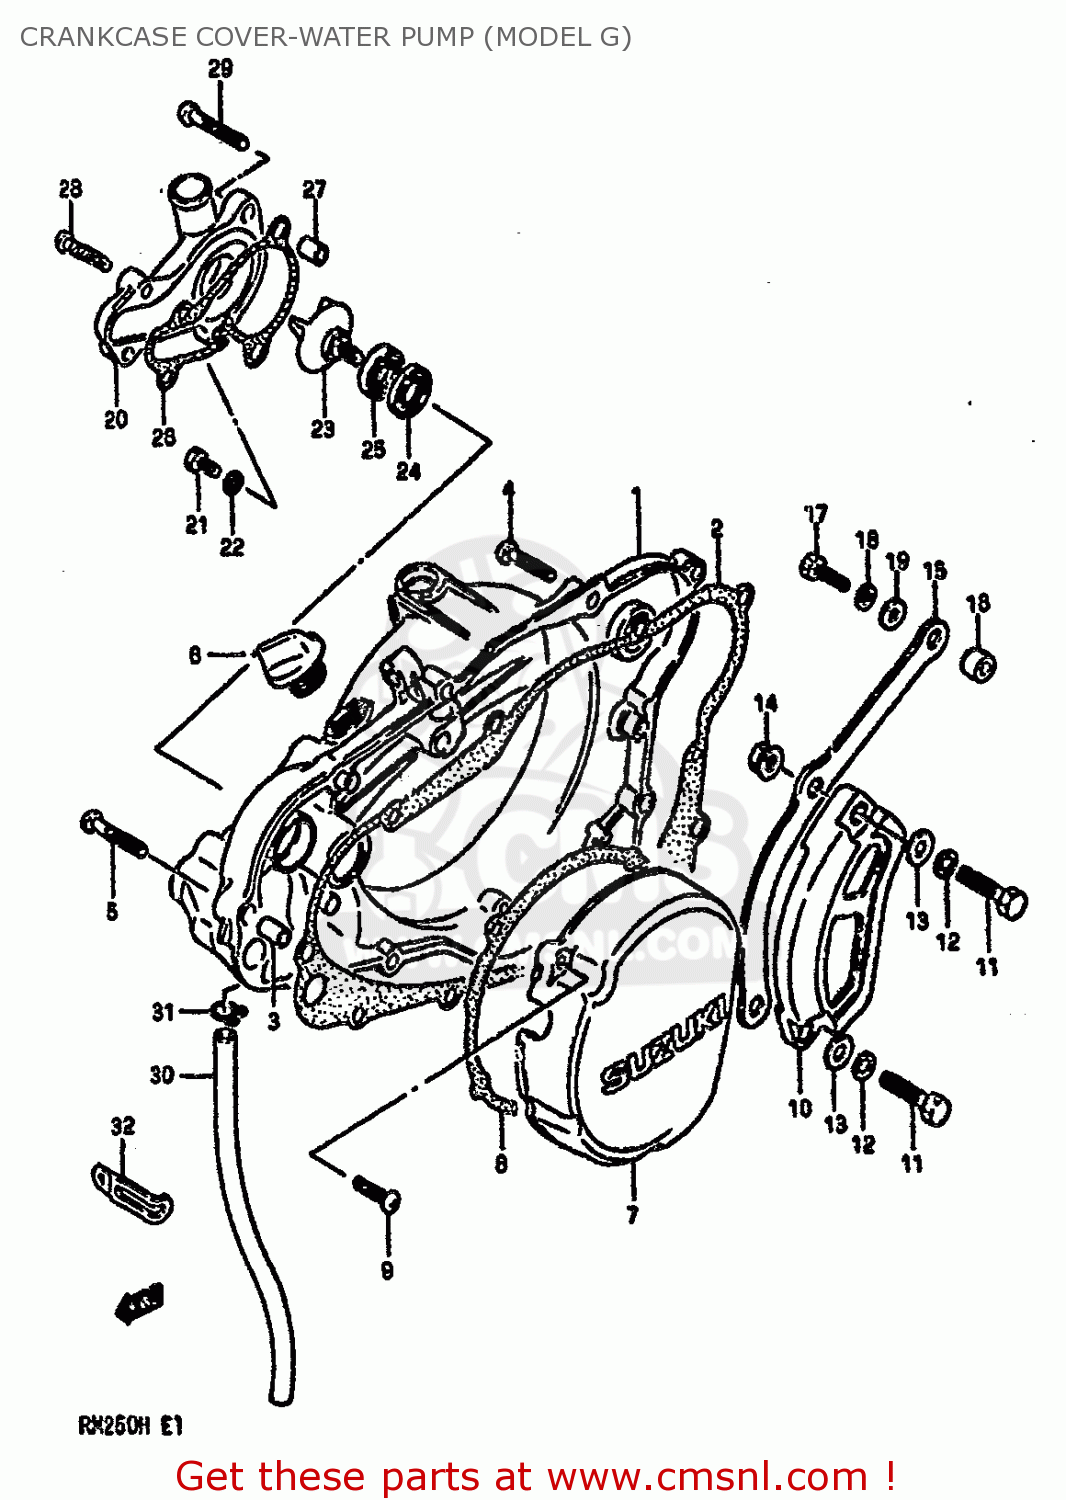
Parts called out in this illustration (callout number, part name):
1	COVER SET,CLUTCH
2	GASKET,CRANKCASE (MCA)
3	PIN
4	SCREW
5	SCREW (6X35)
6	PLUG SET
7	COVER,MAGNETO
8	GASKET,MAGNETO COVER (MCA)
9	SCREW
10	COVER,SPROCKET
11	BOLT (8X30)
12	LOCK WASHER
13	WASHER
14	NUT
15	PLATE,FRONT CHAIN GUIDE
16	SPACER (6.5X12X8)
17	BOLT
18	WASHER,LOCK
19	WASHER
20	CASE COMP,WATER PUMP
21	BOLT,BLEEDER
22	GASKET (NAS)
23	IMPELLER,WATER PUMP
24	SEAL,OIL(12X24X7)
25	SEAL,OIL(12X24X6.4)
26	GASKET,WATER PUMP CASE (MCA)
27	PIN
28	SCREW
29	SCREW 6X30
30	HOSE
31	CLIP
32	CLAMP
